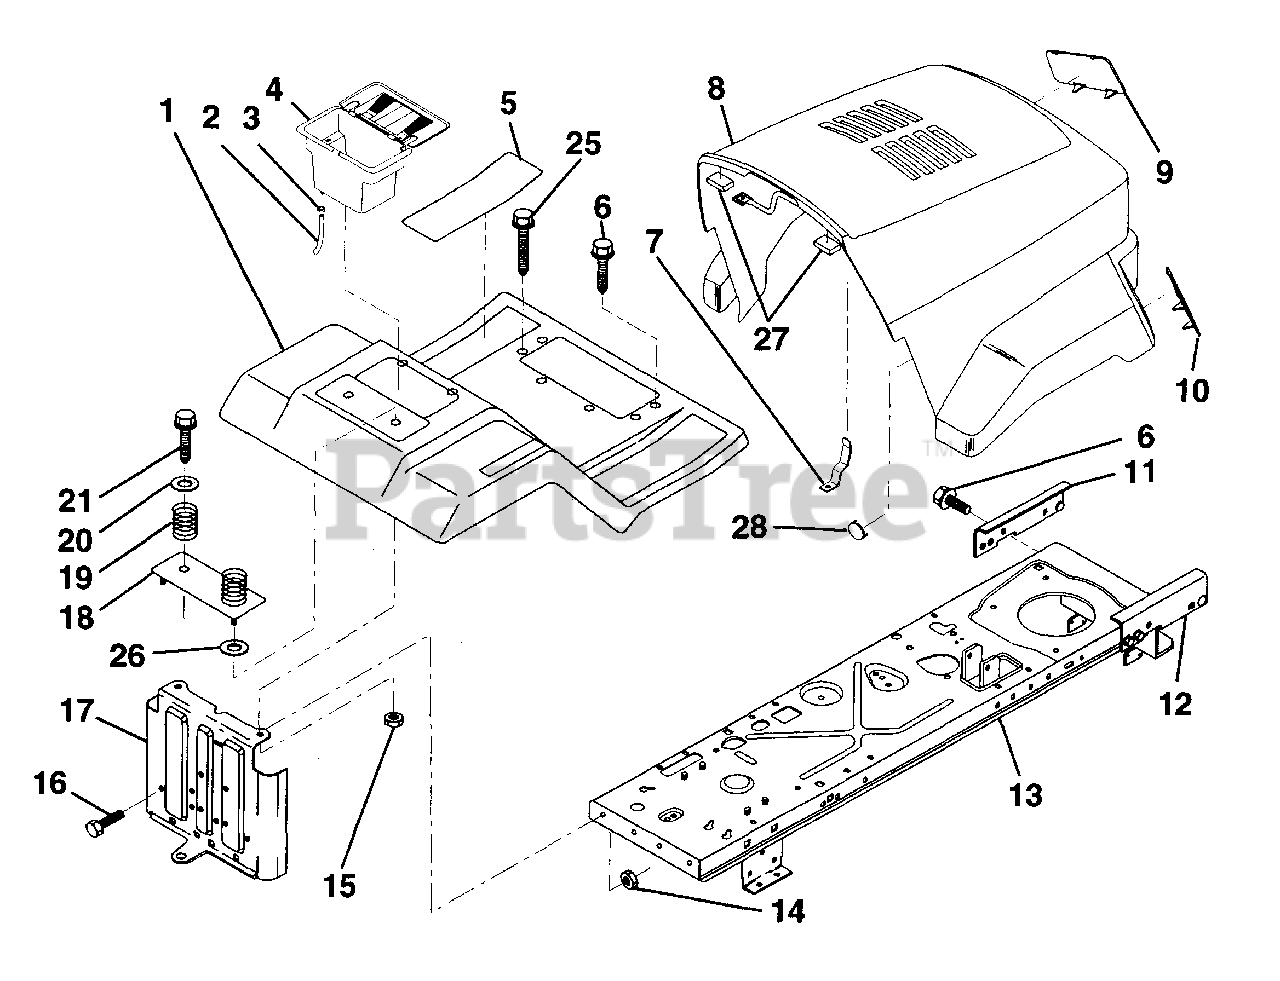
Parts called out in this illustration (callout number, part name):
1	Fender/Footrest
2	Tube, Battery Drain
3	Clamp, Hose
4	Case, Battery
5	Pad, Footrest
6	Screw, Hex Washer Head, Thd., Roll. 5/16-18 x 3/4
7	Latch, Hood
8	Hood/Grill Assembly
9	Lens, L.H.
10	Lens, R.H.
11	Bracket Assy., Pivot, Frame, L.H.
12	Bracket Assy., Pivot, Frame, R.H.
13	Assembly, Frame
14	Nut, Crown lock 5/16-18
15	Nut, Hex, Keps 1/4-20 UNC
16	Bolt, Hex Hd. 5/16-18 UNC x 3/4
18	Plate Assembly, Battery
19	Spring, Compression, Seat
20	Washer 13/32 x 1-1/4 x 12 Gauge
21	Screw, Hex Washer Head, Thd., Roll. 3/8-16 x 3/4
25	Screw, Thrd R15/16 - 18 x 1
26	Washer, 9/32 x 7/8 x 13 Gauge
27	Bumper, Hood
28	Plug, Light Socket
